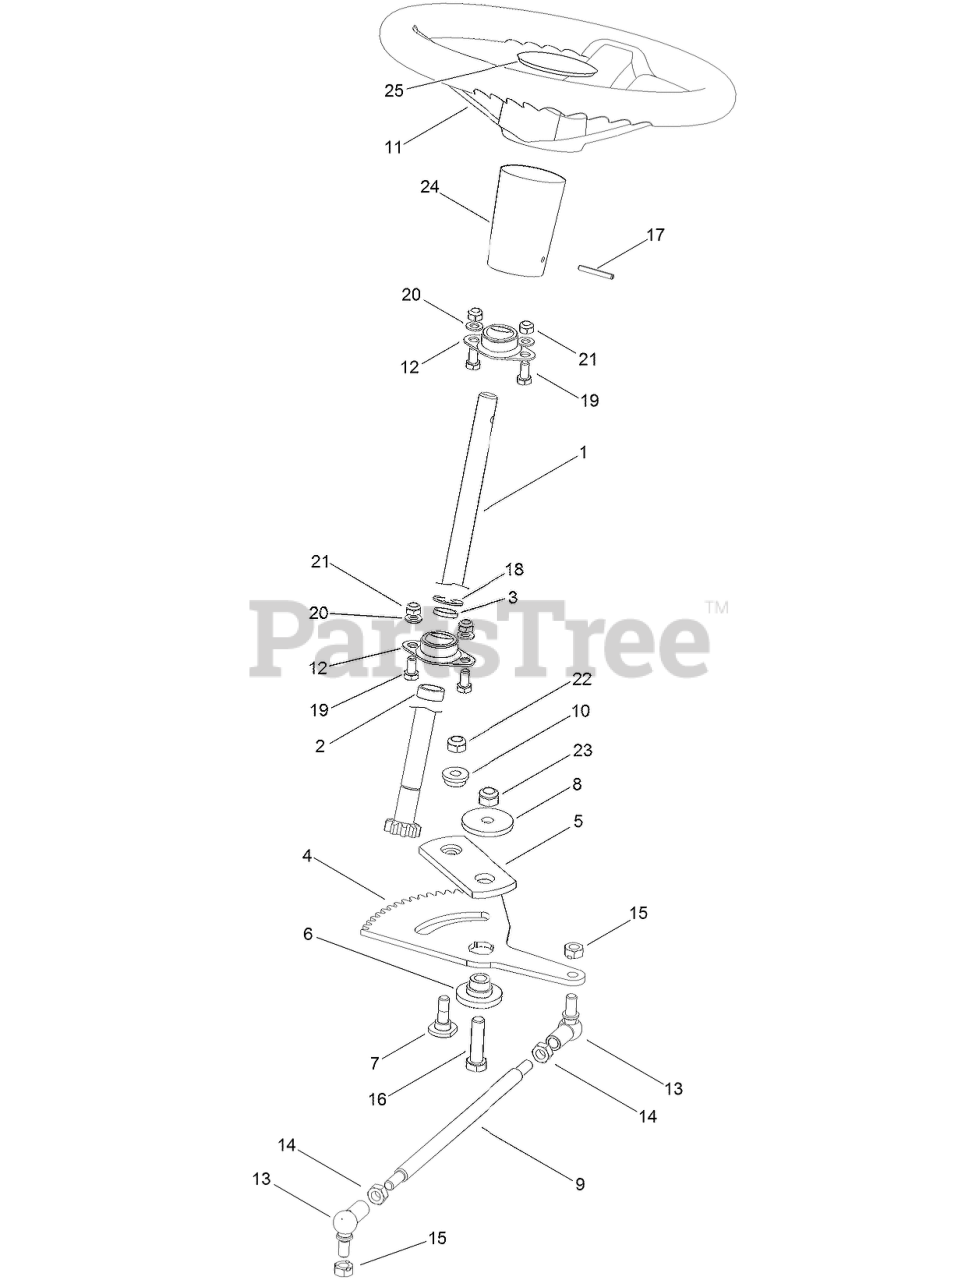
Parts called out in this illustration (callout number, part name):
1	SHAFT-STEERING
2	SPACER-LOWER
3	SPACER-UPPER
4	GEAR-SECTOR
5	Plate-Steering
6	Pivot-Steering
7	Bolt-Shoulder
8	WASHER
9	LINK-DRAG
10	Bushing
11	WHEEL-STEERING
12	BEARING-SPHERICAL
13	JOINT-BALL, ANGLE
14	NUT-HEX
15	Nut-Lock
16	SCREW-HH
17	PIN-SPIROL
18	CLIP-SPRING
19	SCREW-HH
20	WASHER-PLAIN
21	NUT-LOCK, NI
22	NUT-LOCK, NI
23	NUT-HEX
25	CAP-WHEEL, STEERING
